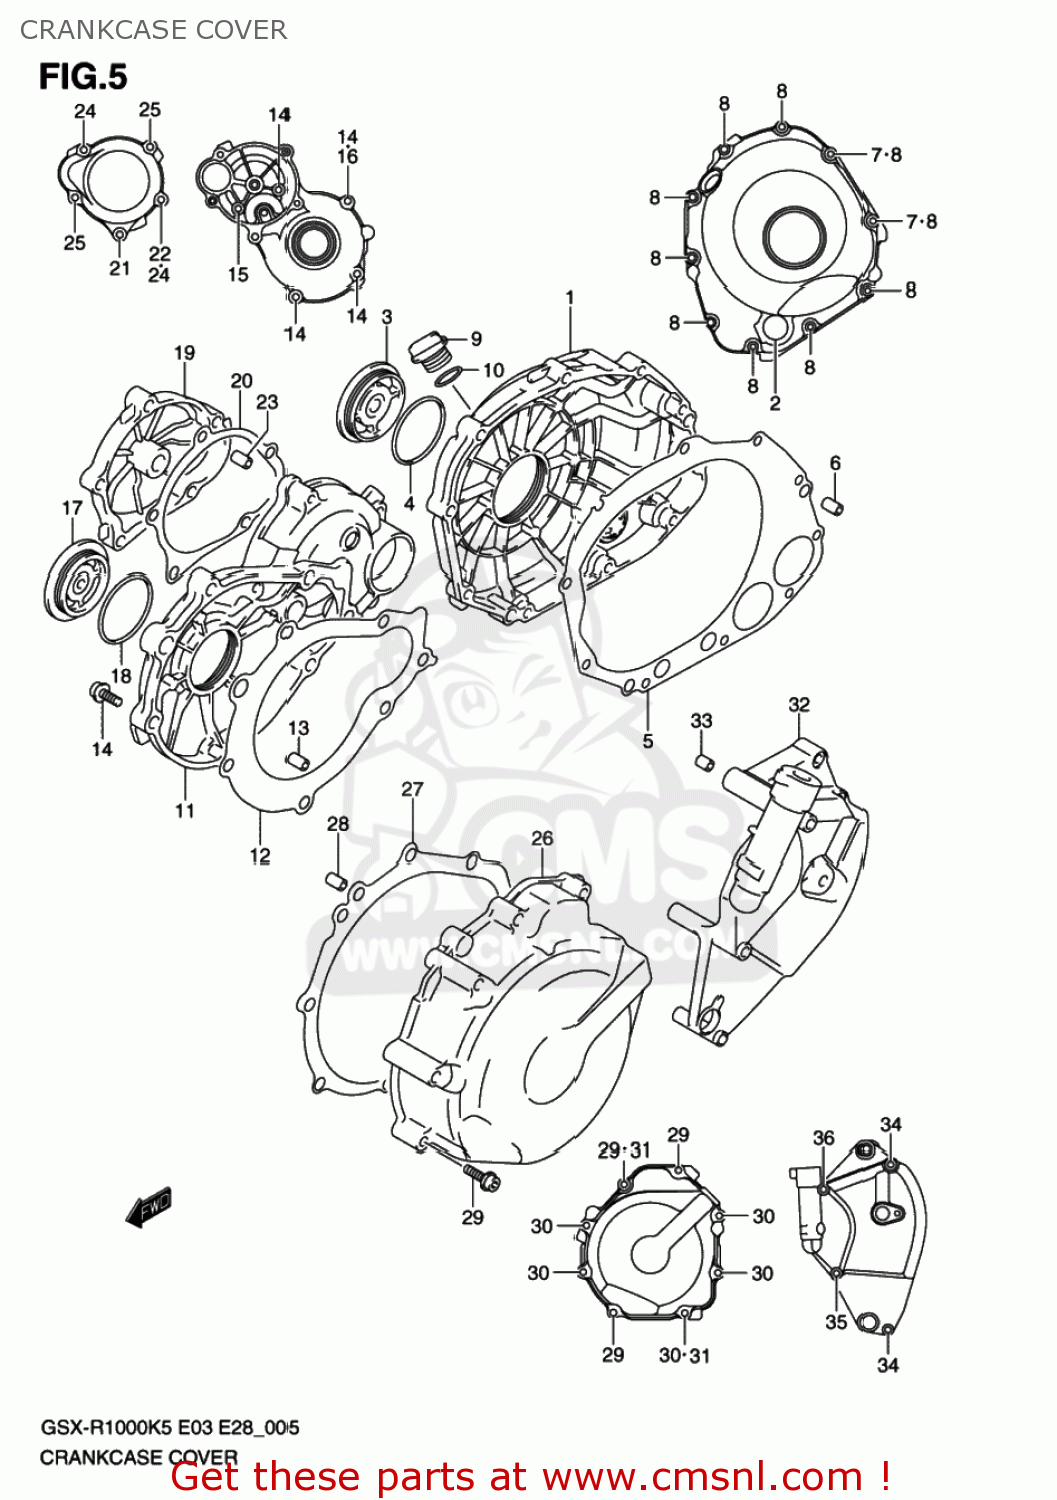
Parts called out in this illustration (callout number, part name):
1	COVER,CLUTCH
2	LENS,OIL LEVEL CHECK
3	CAP,CLUTCH RELEASE ADJUST
4	O RING(D:2.4,ID:52.6)
5	GASKET,CL COVE (NAS)
6	PIN
7	GASKET(5.8X13X1.2) (NAS)
8	BOLT,G/S SWITC
9	PLUG,ENGINE OIL FILLER
10	O RING(D:3.1,ID:16.8)
11	COVER,STARTER CLUTCH
12	GASKET,STARTER CLUTCH COVER
13	PIN
14	SCREW
15	BOLT
16	GASKET(5.8X13X1.2) (NAS)
17	PLUG
18	O RING(D:3.1,ID:32.7)
19	CAP,STARTER IDLE GEAR
20	GASKET,START IDLE GEAR CAP (NAS)
21	BOLT
22	GASKET(5.8X13X1.2) (NAS)
23	PIN
24	SCREW
25	BOLT
26	COVER,MAGNETO
27	GASKET,MAGNETO COVER (NAS)
28	PIN
29	BOLT,G/S SWITC
30	BOLT
31	GASKET(5.8X13X1.2) (NAS)
32	COVER,ENGINE SPROCKET
33	PIN
34	BOLT
35	BOLT
36	BOLT
